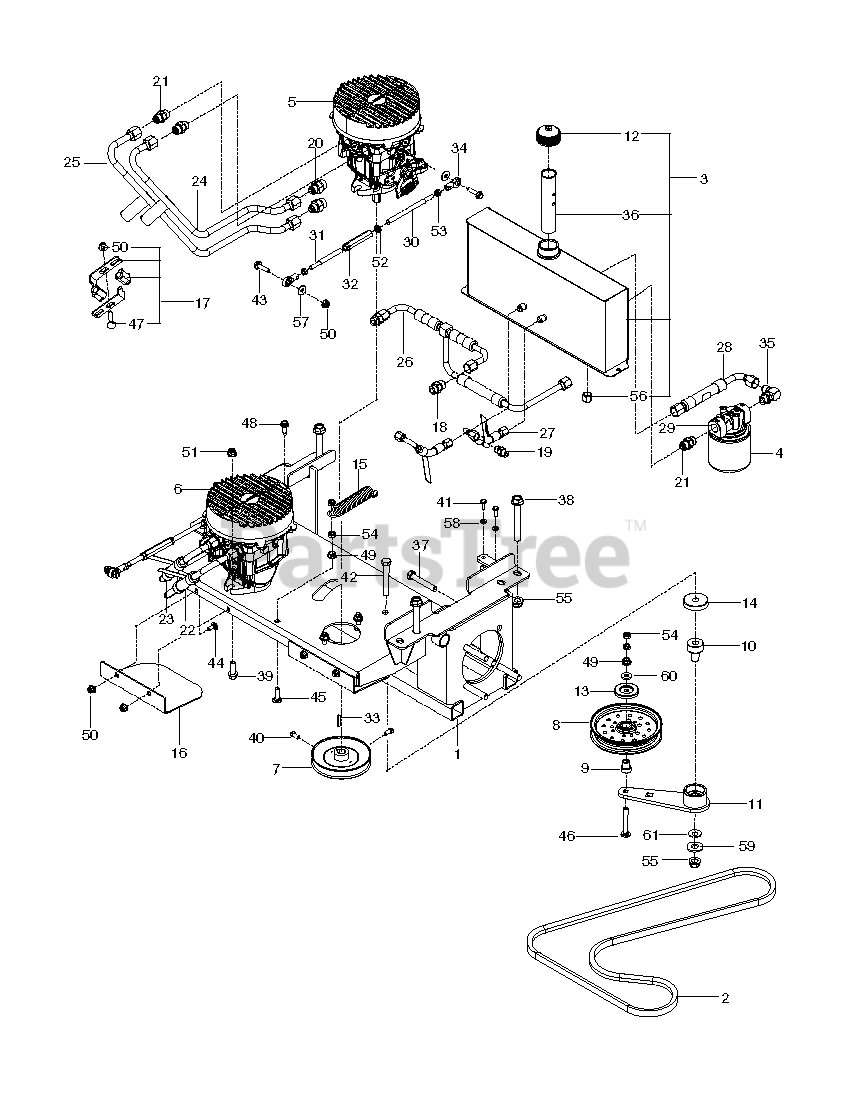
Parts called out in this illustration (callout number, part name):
1	FRAME, NYDR SUB, BLK
2	BELT, "B", 75.5"
3	ASSEMBLY, RESERVOIR, OIL
4	FILTER 25 MICRON
5	HG_PUMP, 12CC RT
6	HG_PUMP, 12CC LT
7	PULLEY, PUMP 15MM
8	IDLER, FLAT, 5.5"
9	PIVOT, IDLER
10	PIVOT, BEARING
11	ARM, IDLER, STEEL, W/BGS
12	CAP, HYDRAULIC
13	DUST SHIELD
14	SHIELD, DUST
15	SPRING, PUMP
16	SHIELD, PULLEY, BLK
17	ASM, VIB, HYDRO HOSE
18	FITTING, HYDRO
19	STRAIGHT FITG
20	CONNECTOR, STRAIGHT
21	FITTING, STRAIGHT F6400-8-8-0
22	LINE, RT A
23	LINE, RT B
24	LINE, LT A
25	LINE, LT B
26	LINE, CHARGE
27	LINE, CASE
28	LINE, SUCTION
29	FILTER HEAD
30	LINKAGE, CONTROL, RR
31	LINKAGE, CONTROL, FT
32	TURNBUCKLE, 3/8
33	KEY 5 MM SQ X 25 MM
34	BALL JOINT, RIGHT HANDED
35	ELBOW, 90 DEGREE
36	TUBE, ANTI-SPLASH
37	HCS 1/2C X 2 3/4
38	HHFS 1/2-13 X 4.0 GD8 ZD
39	HHFS 3/8-16 X 1.25 GD 5
40	SCREW 5/16C X 5/8 SQ HEAD
41	HCS 1/4C X 5/8
42	HCS 1/2C X 3 1/4
43	HHFS 5/16-18 X 1.25 TPBLT GD 5
44	BOLT 5/16C X 3/4" CARRIAGE
45	RHSNB 3/8-16 X 1-1/4
46	RHSNB 3/8-16 X 2.75
47	RHSNB 5/16-18 X 1-1/2 GR 5 ZD
48	RP BLT 5/16-18 X 1 THRD FORM D
49	NUT 3/8C WHIZ
50	5/16-18 NYLOC FLANGE NUT
51	NUT 3/8-16 HEX FLG NYLOC ZD
52	NUT 3/8-24 JAM
54	NUT HEX 3/8-16 NYLON, THIN
55	NUT, 1/2-13 HEX FLG NYLOC ZD
56	NUT 9/16-18 JIC CAP
57	WASHER 5/16 FLAT
58	LOCKWASHER 1/4"
59	WASH USS FLAT 1/2
60	WASHER, 3/8 THICK
61	CONTACT BELLSPR 1/2
